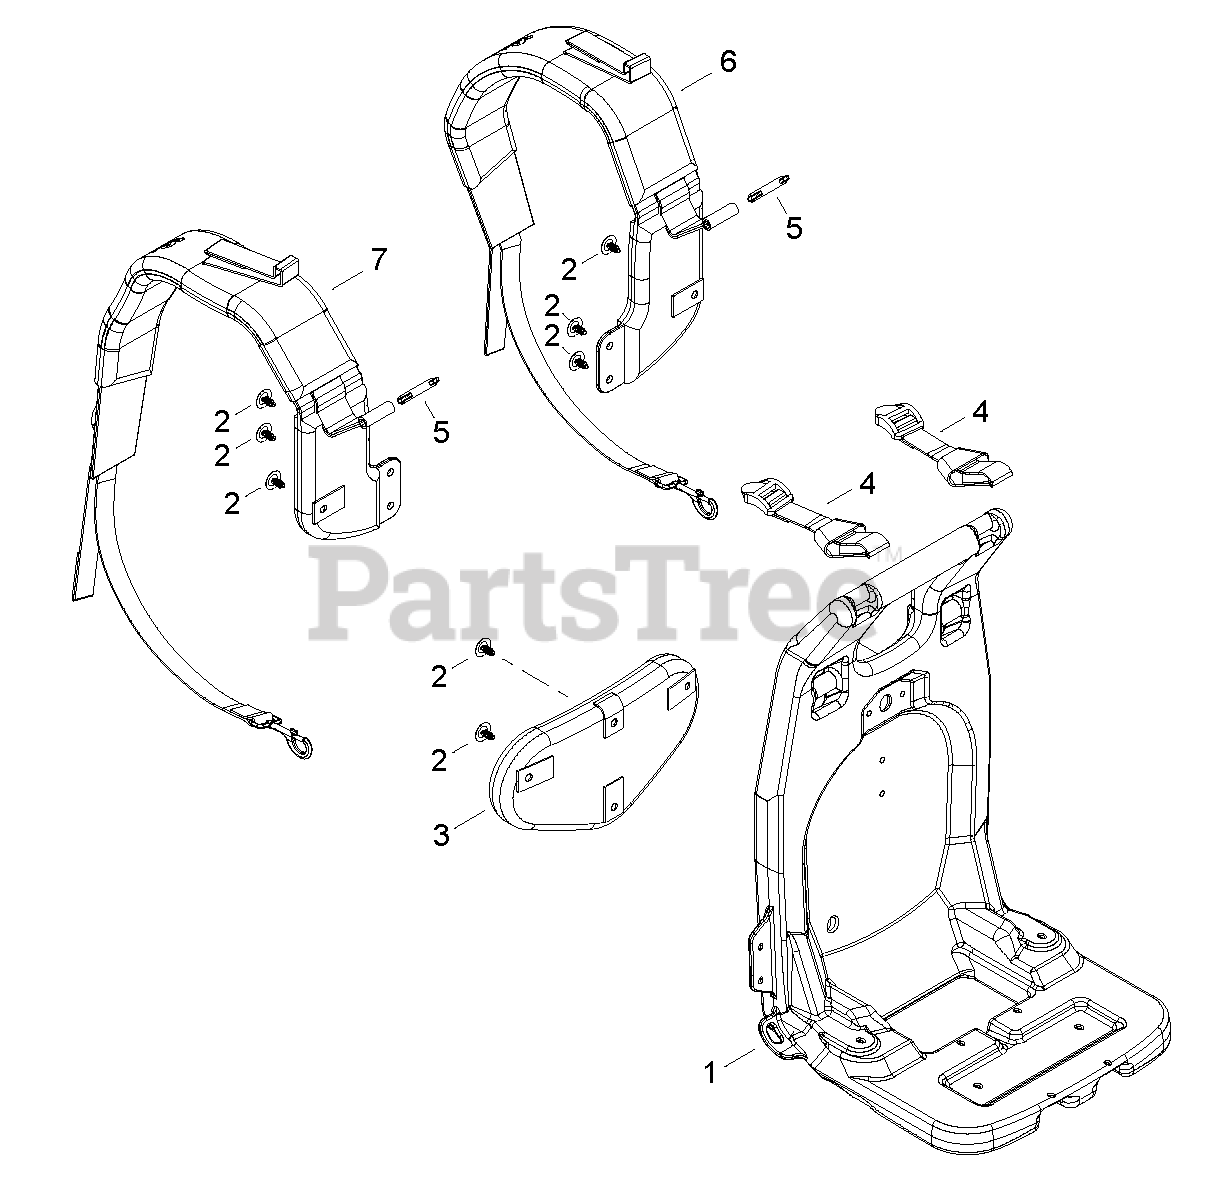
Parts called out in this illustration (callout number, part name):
1	FRAME, BACKPACK
2	CLIP
3	CUSHION, BACKPACK
4	CONNECTOR, STRAP
5	RING, HARNESS
6	HARNESS - RIGHT
7	HARNESS - LEFT
